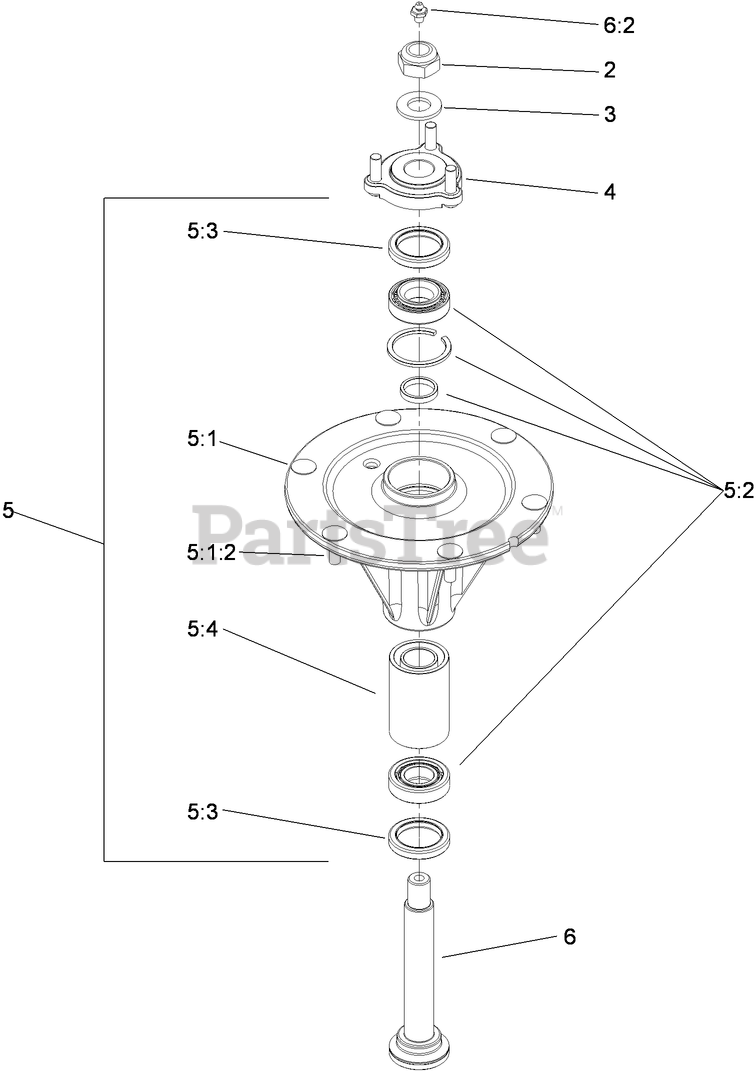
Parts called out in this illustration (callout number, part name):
2	NUT-LOCK, NI
3	WASHER
4	SPINDLE HUB ASM
5	SPINDLE HOUSING AND TAPERED BEARINGS ASM
5:1	HOUSING-SPINDLE
5:1:2	BOLT-RIBBED NECK
5:2	BEARING ASM
5:3	SEAL-OIL
5:4	SPACER SET
6	SPINDLE SHAFT AND ZERK ASM
6:2	FITTING-GREASE
